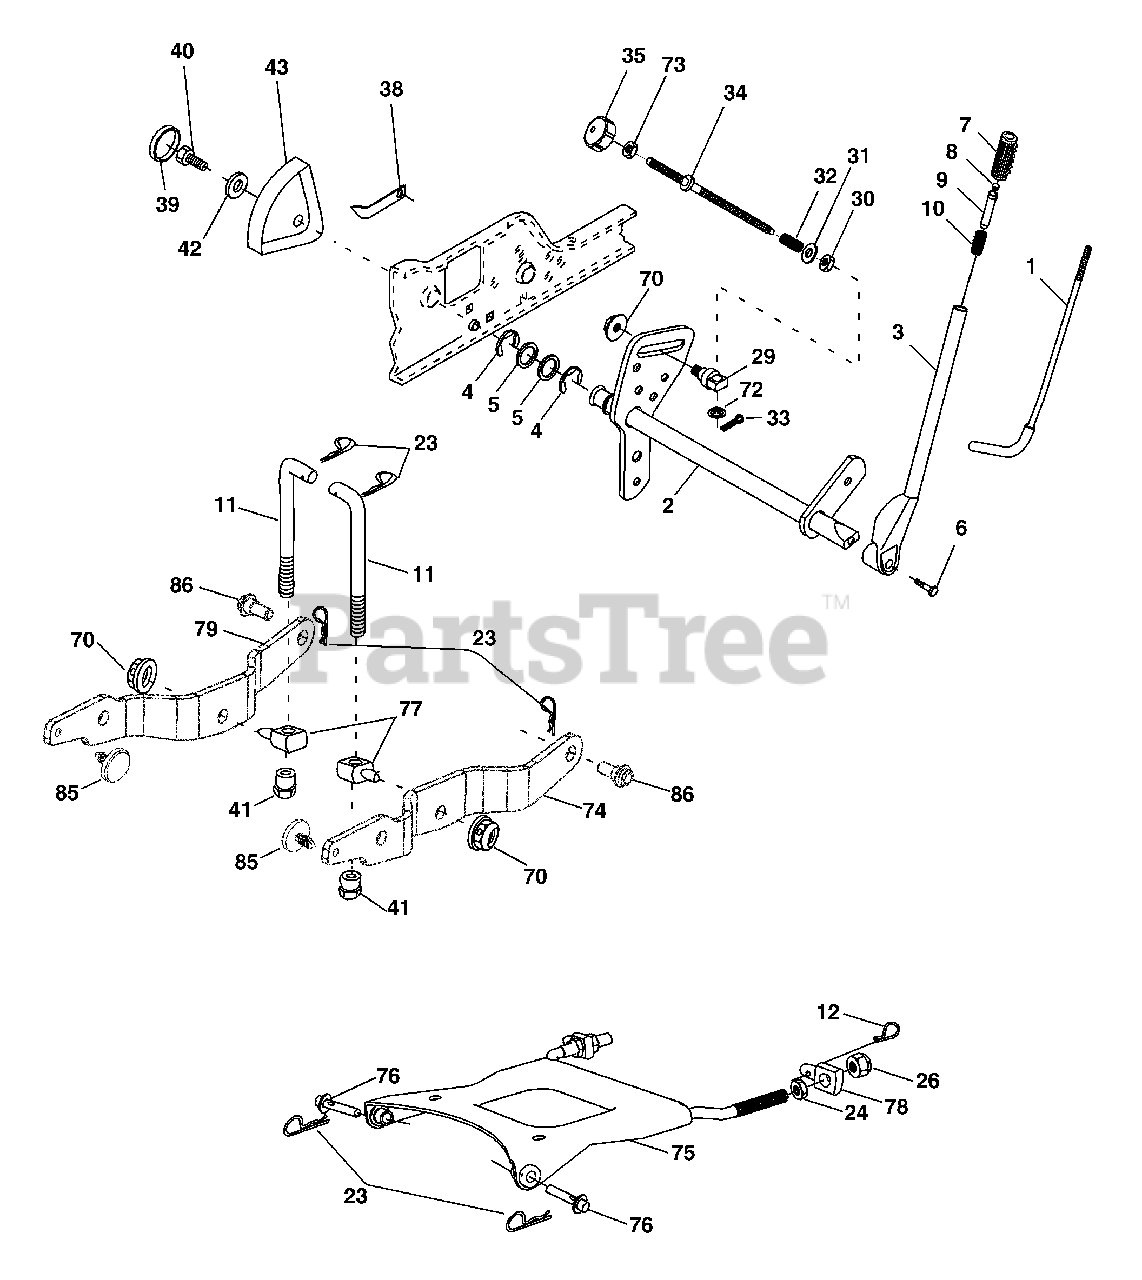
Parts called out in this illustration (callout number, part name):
1	Rod Asm., Lever
2	Shaft Asm., Lift Vgt
3	Lever Asm., Lift Rh
4	E-Ring Truarc #5133-87
5	Washer 29/32 x 1-1/4 x 16 Ga.
6	Bolt, Fin Hex 3/8-16 x 1-1/2
7	Grip, Handle
8	Button, Plunger
9	Plunger Lever Lift
10	Spring 0.62 OD x 2.125
11	Link Lift
12	Retainer, Spring
23	Retainer, Spring
24	Nut, Jam Hex 1/2-13 unc
26	Nut, Crownlock 1/2-13 unc
29	Trunnion Inf. Height
30	Nut, Special
31	Washer 13/32 x 5/8 x 16 Ga.
32	Spring, Compression Inf Hgt
33	Pin, Cotter 3/32 x 1/2
34	Rod, Adj Lift
35	Knob, Inf 3/8-16 unc
38	Pointer, Height Indicator
39	Plug, Hole
40	Screw 5/16-18 x 3/4
41	Nut, Lift Link 7/16-20
42	Washer 11/32 x 1-1/2 x 10 Ga.
43	Scale, Indicator Height
70	Nut, Hexflange Lock
72	Nut, Push Phos & Oil
73	Nut Hex Jam 3/8-16 unc
74	Arm Susp. Rear RH
75	Plate Asm Susp. Front
76	Pin Flange
77	Trunnion Susp. Arm
78	Trunnion Susp. Front
79	Arm Susp. Rear LH
85	Insert Wear
86	Bolt Shoulder
